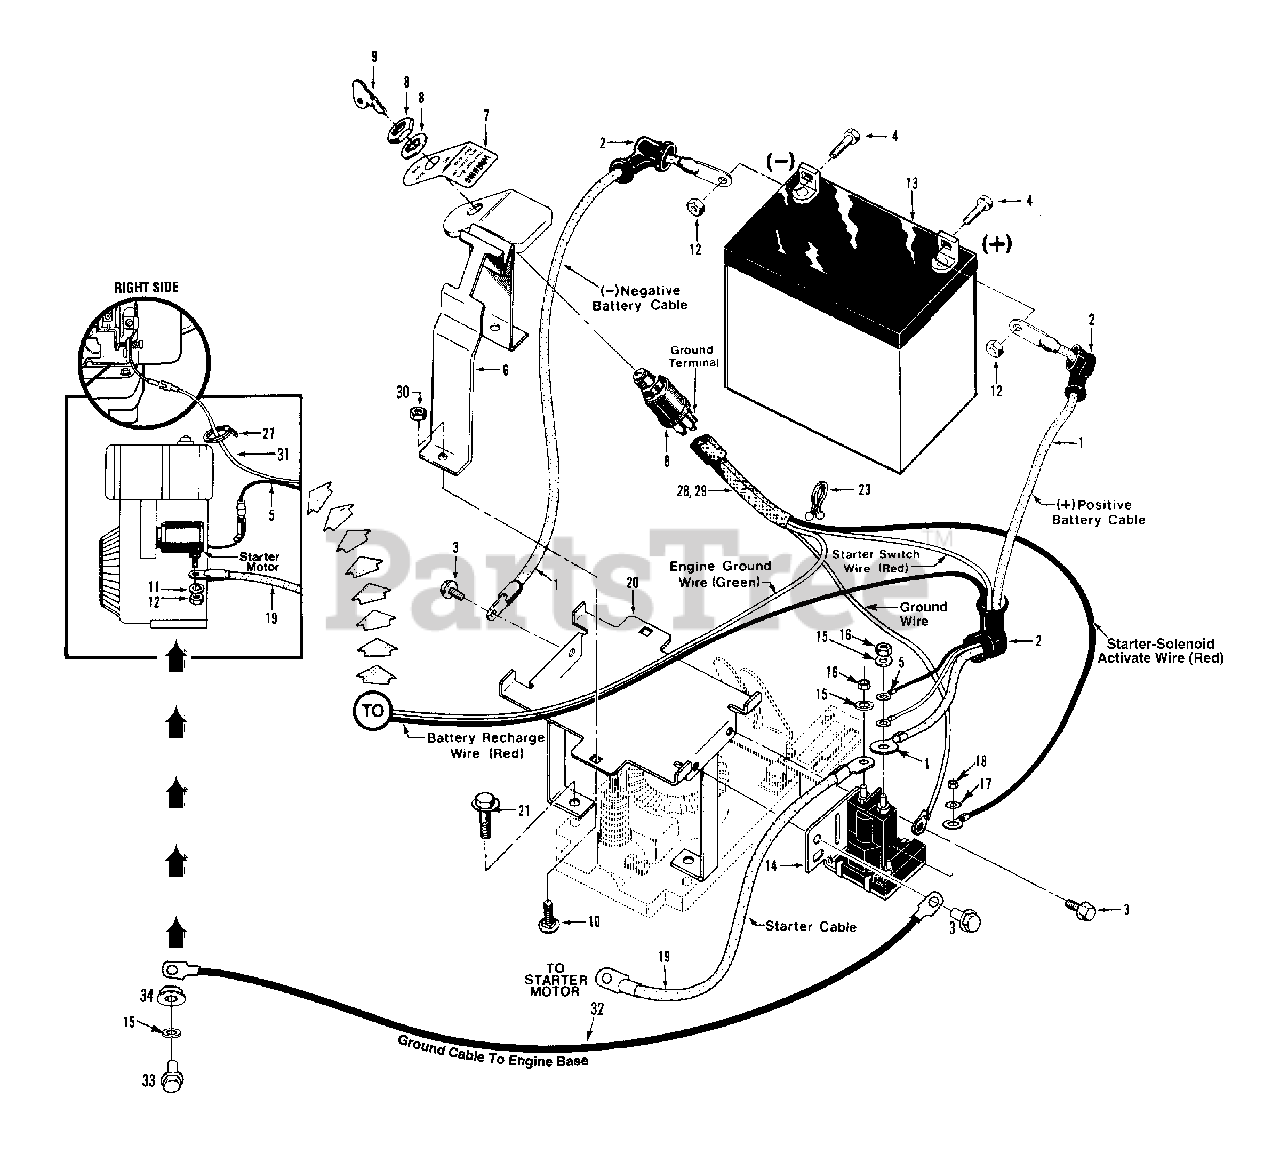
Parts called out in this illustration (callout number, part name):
1	Cable-battery, positive and negative terminals
2	Boot-terminal insulating
3	Screw-self-threading, 1/4-20 x 1/2"
4	Bolt-hex hd., 1/4-20 x 5/8"
5	Wire-recharge (red)
6	Battery Hold-down Clamp-with attached Key Switch Plate
7	Decal-ignition switch instruc.
8	Key Switch
9	Key-ignition, one pair
10	Bolt-carriage, 1/4-20 x 1-1/4"
11	Lockwasher-spring lock, 1/4"
12	Nut-hex, 1/4"-20
13	Battery-12 volt, 270 CCA.
14	Solenoid-starter
15	Lockwasher-5/16"
16	Nut-hex, 5/16"-24
17	Lockwasher-external tooth, #10
18	Nut-hex, #10-32,
19	Cable-solenoid to starter motor
20	Battery Bracket
21	Bolt-flanged hex hd., 3/8-16 x 1-1/2"
23	Tie-plastic, wire retaining
27	Tie-plastic
28	Wire Harness & Connecting Terminal Assembly
30	Locknut-hex, 1/4"-20
31	Ground Wire Assembly
32	Cable-ground, solenoid to engine block
33	Bolt-flange lock, 5/16-18 x 1"
34	Nut-flange lock, 5/16"-18
